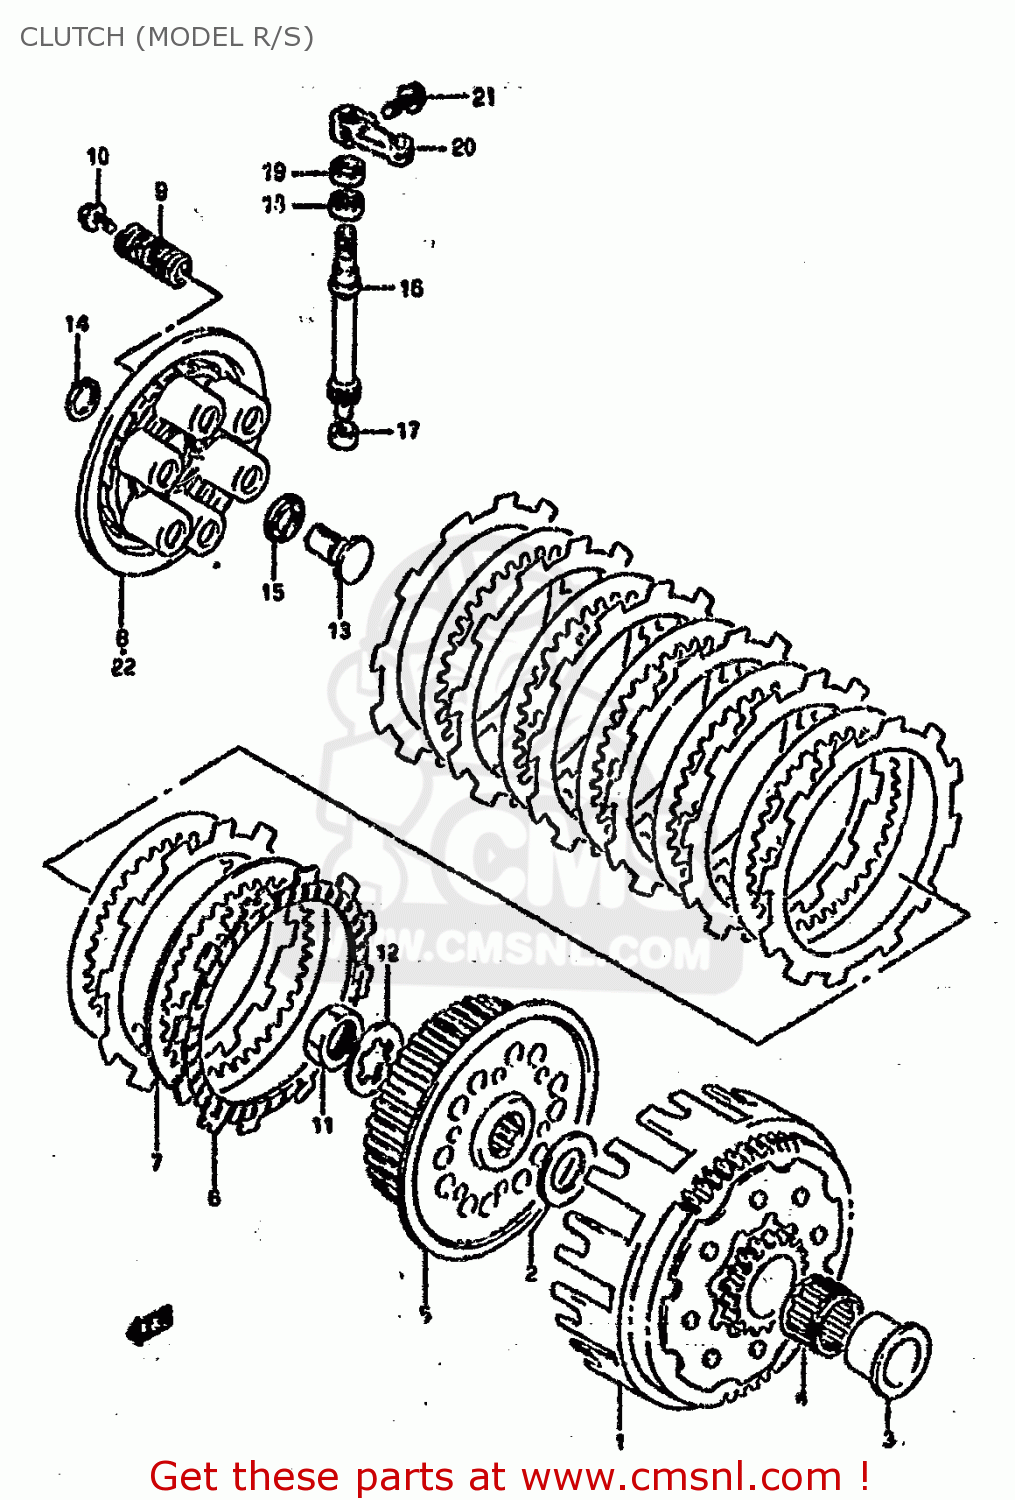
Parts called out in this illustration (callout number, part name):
1	GEAR ASSEMBLY,PRIMARY DRIVE
2	WASHER(22X38X2)
3	SPACER,PRIMARY DRIVEN GEAR
4	BEARING(29X34X21.8)
5	HUB,CLUTCH SLEEVE
6	PLATE,CLUTCH DRIVE (NAS)
7	PLATE,CLUTCH DRIVEN T: (NAS)
8	DISC,CLUTCH PRESSURE
9	SPRING
10	BOLT(5X25)
11	NUT
12	WASHER,LOCK
13	RACK,CLUTCH RELEASE
14	CIRCLIP,10MM
15	BEARING(10X22X2.8)
16	PINION,CLUTCH RELEASE(NT:12)
17	BEARING(9X13X10)
18	BEARING(12X16X10)
19	SEAL,OIL(10X17X5)
20	ARM,CLUTCH RELEASE
21	BOLT
22	DISC,CLUTCH PRESSURE
